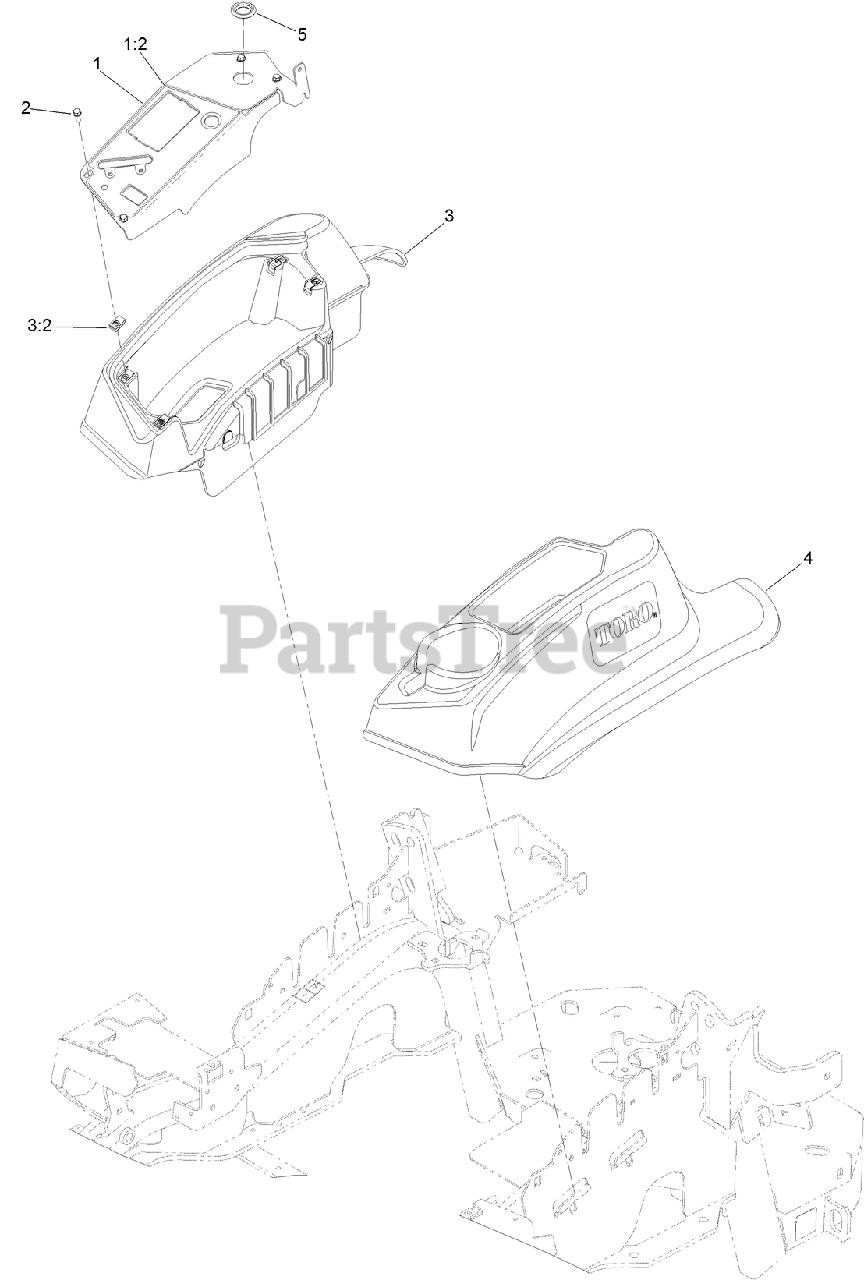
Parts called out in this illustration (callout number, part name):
1	CONTROL PANEL ASM
1:2	DECAL-PANEL, CONTROL
2	SCREW-HWH
3	RH CONSOLE ASM
4	CONSOLE-LH
5	PLUG-PLASTIC
